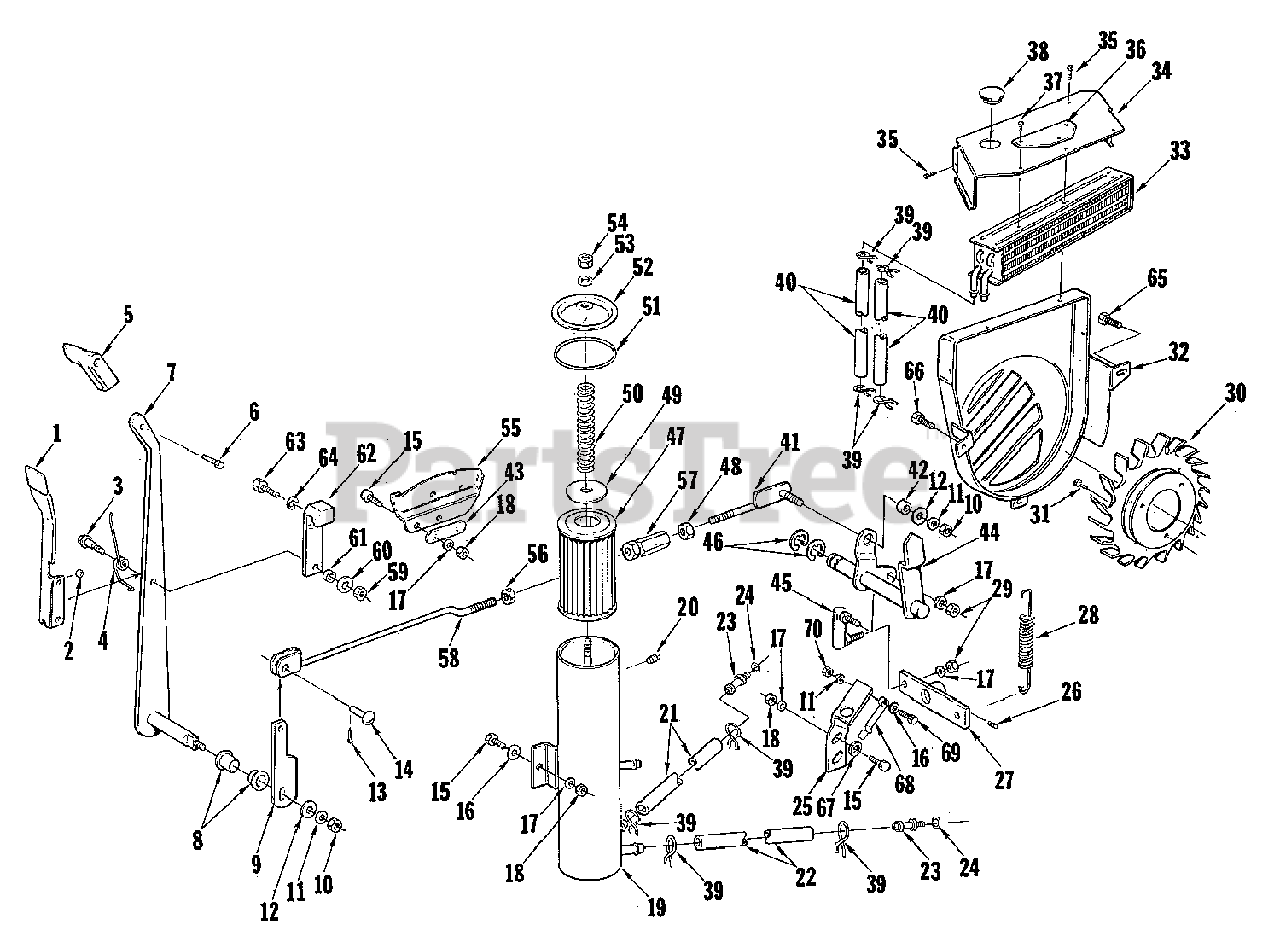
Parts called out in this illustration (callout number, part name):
1	HANDLE, Trip
2	BALL, Shift Handle
3	BOLT, Shoulder
6	SCREW, Thread Cutting, 1/4-20 x 7/8
7	LEVER ASSEMBLY, Speed Control
8	BUSHING, Flanged
9	LINK, Speed Control
10	NUT, Hex Fin, 3/8
11	WASHER, Lock, 3/8
15	SCREW, Hex Head Cap, 5/16-18 x 3/4
16	WASHER, Flat, 5/16
17	WASHER, Lock, 5/16
18	NUT, Hex Fin, 5/16-18
19	RESERVOIR ASSEMBLY
20	PLUG, Plastic
21	HOSE, Hydraulic
22	HOSE, Hydraulic
23	INSERT, Beaded
25	SUPPORT, Switch
27	LINK ASSEMBLY, Control
29	NUT, Hex Fin, 5/16-24
31	SCREW, Hex Washer Head, 1/4-20 x 1/2
32	SHROUD ASSEMBLY, Fan
34	DEFLECTOR, Cooler
35	SCREW, Self Tapping Hex, 10 x 3/8
36	CLIP, Spring
37	SCREW, Round Head, 10-32 x 1/2
40	HOSE, Hydraulic
41	ROD ASSEMBLY, Speed Control
43	SPACER, Speed Control Quadrant
44	SHAFT ASSEMBLY, Control
45	JOINT, Ball (Double End)
47	ELEMENT, Filter
48	NUT, Hex, 7/16-14 (L.H. Thread)
52	COVER, Reservoir
53	WASHER, Nylon
54	NUT, Lock, 5/16-18, ESNA
55	QUADRANT, Speed Control
56	NUT, Hex Fin, 7/16-14 (R.H.)
58	ROD ASSEMBLY, Speed Control (Front)
59	NUT, Hex Lock, 1/4-20
60	WASHER, Standard, 1/4
63	SCREW, Hex Head Cap, 1/4-20 x 1/2
64	WASHER, Lock, Regular, 1/4
65	SCREW, Hex Cap, 5/16-18 x 7/8
66	SCREW, Self Tapping Hex, 5/16 x 5/8
67	WASHER, Flat, 7/16
68	CLIP, Switch
69	BOLT, Shoulder
70	NUT, Jam, 3/8-16
